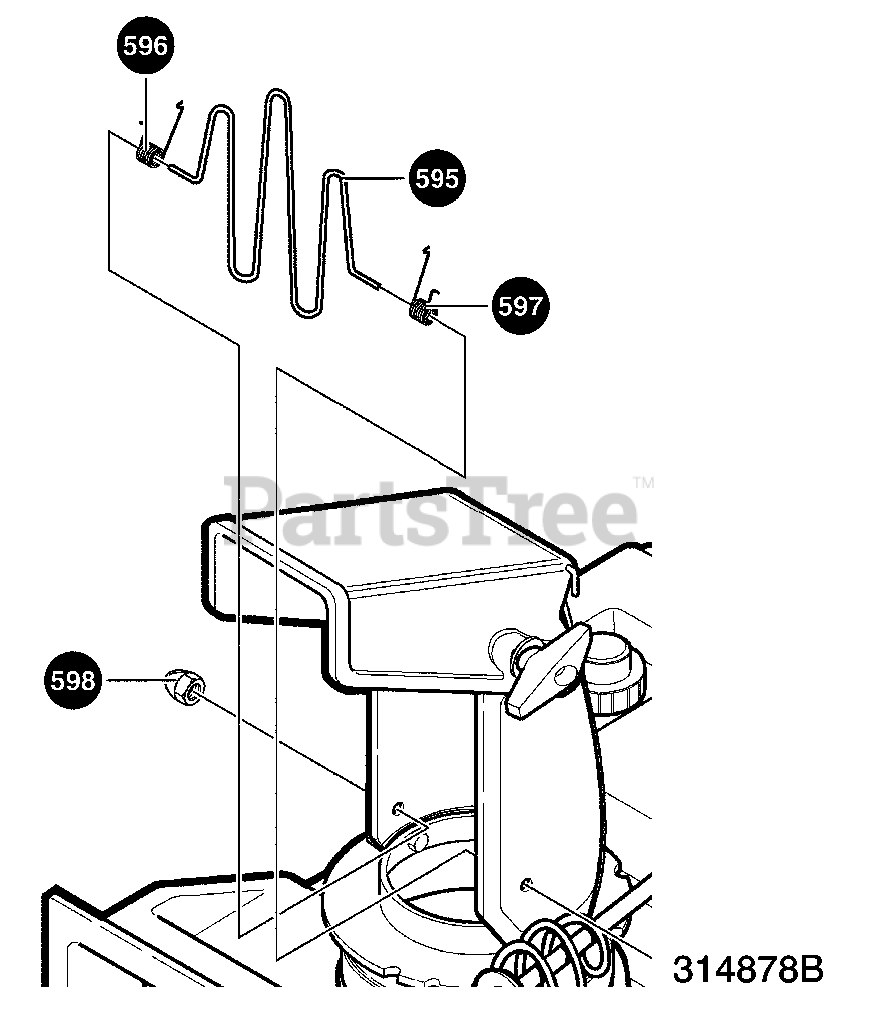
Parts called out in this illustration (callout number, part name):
595	GUARD, WIRE CHUTE
596	SPRING, TORSION
597	SPRING, TORSION
598	NUT, ACORN
